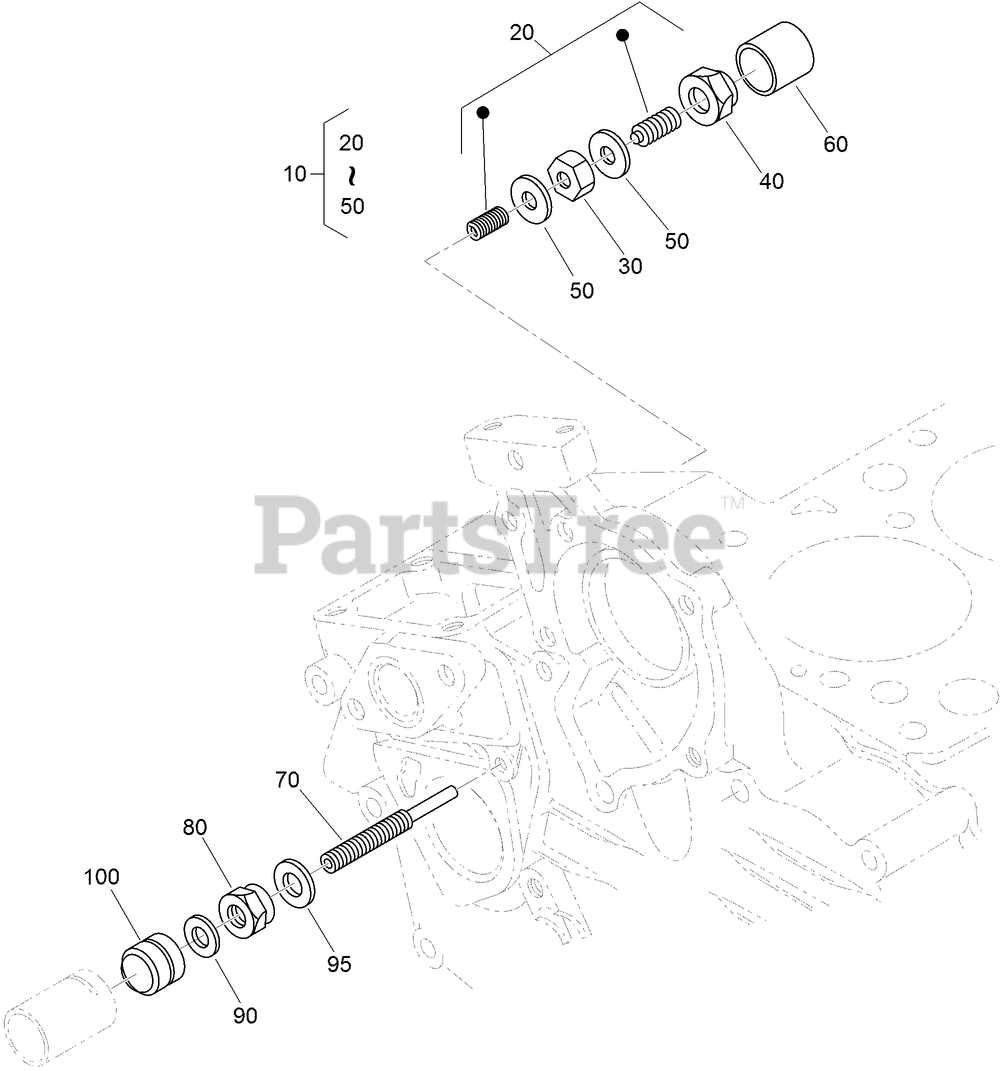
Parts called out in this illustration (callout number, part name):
10	IDLE APPARATUS ASM
20	ADJUSTING BOLT ASM
40	NUT-CAP
50	GASKET
70	BOLT-ADJUSTING
80	NUT-LOCK
90	GASKET
95	GASKET
100	NUT-CAP
